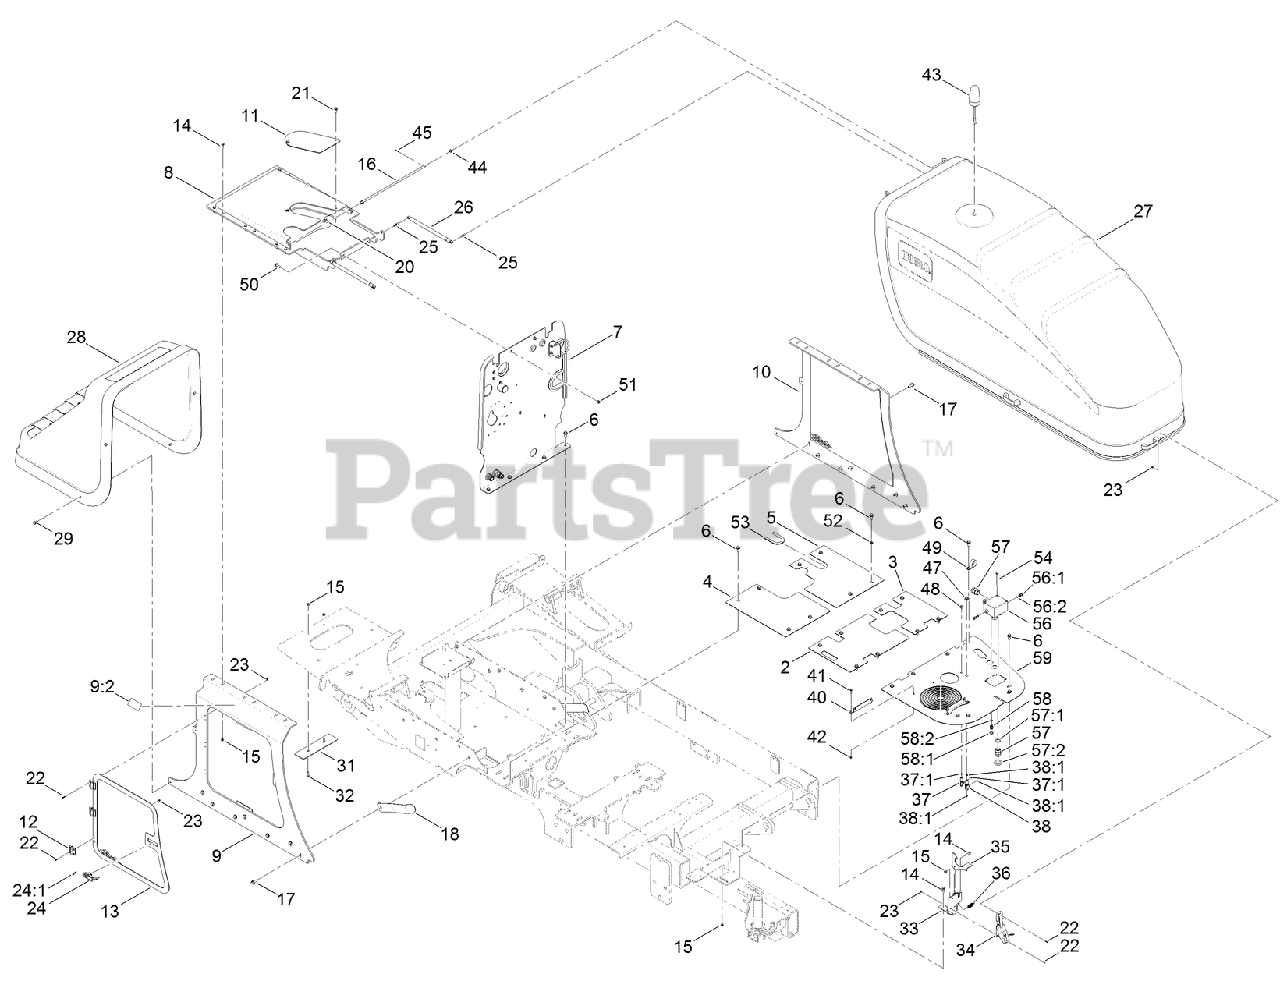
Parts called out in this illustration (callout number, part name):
2	PLATE-SEAL, HOOD
3	PLATE-SEAL, HOOD
4	PLATE-HOOD SEAL
5	PLATE-HOOD SEAL
6	SCREW-HHF
7	BULKHEAD ASM
8	MOUNTING-HOOD
9	HOOD MOUNTING ASM
9:2	DECAL-WARNING, HOT SURFACE
10	MOUNT-HOOD
11	PLATE-COVER
13	DOOR-SIDE
14	SCREW-HHF
15	NUT-LOCK, HHF
16	PIN-MOUNT, HOOD
17	SCREW-HHF
18	GUIDE-HOOD
21	SCREW-HHF
22	SCREW-PRH
23	NUT-KEPS
24	LATCH-TRIGGER, RAISED (W/LOCK)
24:1	KEY-REPLACEMENT
25	STUD-BALL
26	SPRING-GAS
27	FRONT HOOD ASM
28	REAR HOOD ASM
29	SCREW-HHF
31	PLATE-SANDWICH, HOOD STOP
32	SCREW-HHF
33	MOUNT-HOOD, SAFETY LATCH
34	LATCH-DRAW, LOCKABLE
35	HOOK-HOOD, SAFETY LATCH
36	SPRING-TENSION
37	FITTING-TEE
37:1	O-RING
38	FITTING-TEE, BULKHEAD
38:1	O-RING
40	PLATE-MOUNT, FAN
41	SCREW-HHF
42	NUT-FLANGE, NI
43	LIGHT-STROBE
44	WASHER-THRUST
45	PIN-COTTER
47	NUT-LOCK
48	NUT-LOCK
49	CLAMP-R
50	SCREW-HHF
51	NUT-LOCK, NI
52	WASHER-LOCK, EXT
53	TRIM-TANK
54	SCREW-HHF
56	MANIFOLD-VALVE
56:1	VALVE-POPPET
56:2	SEAL KIT
57	FITTING-STRAIGHT
57:1	O-RING
57:2	O-RING
58	FITTING-STRAIGHT
58:1	O-RING
58:2	O-RING
59	PLATE-BULKHEAD
